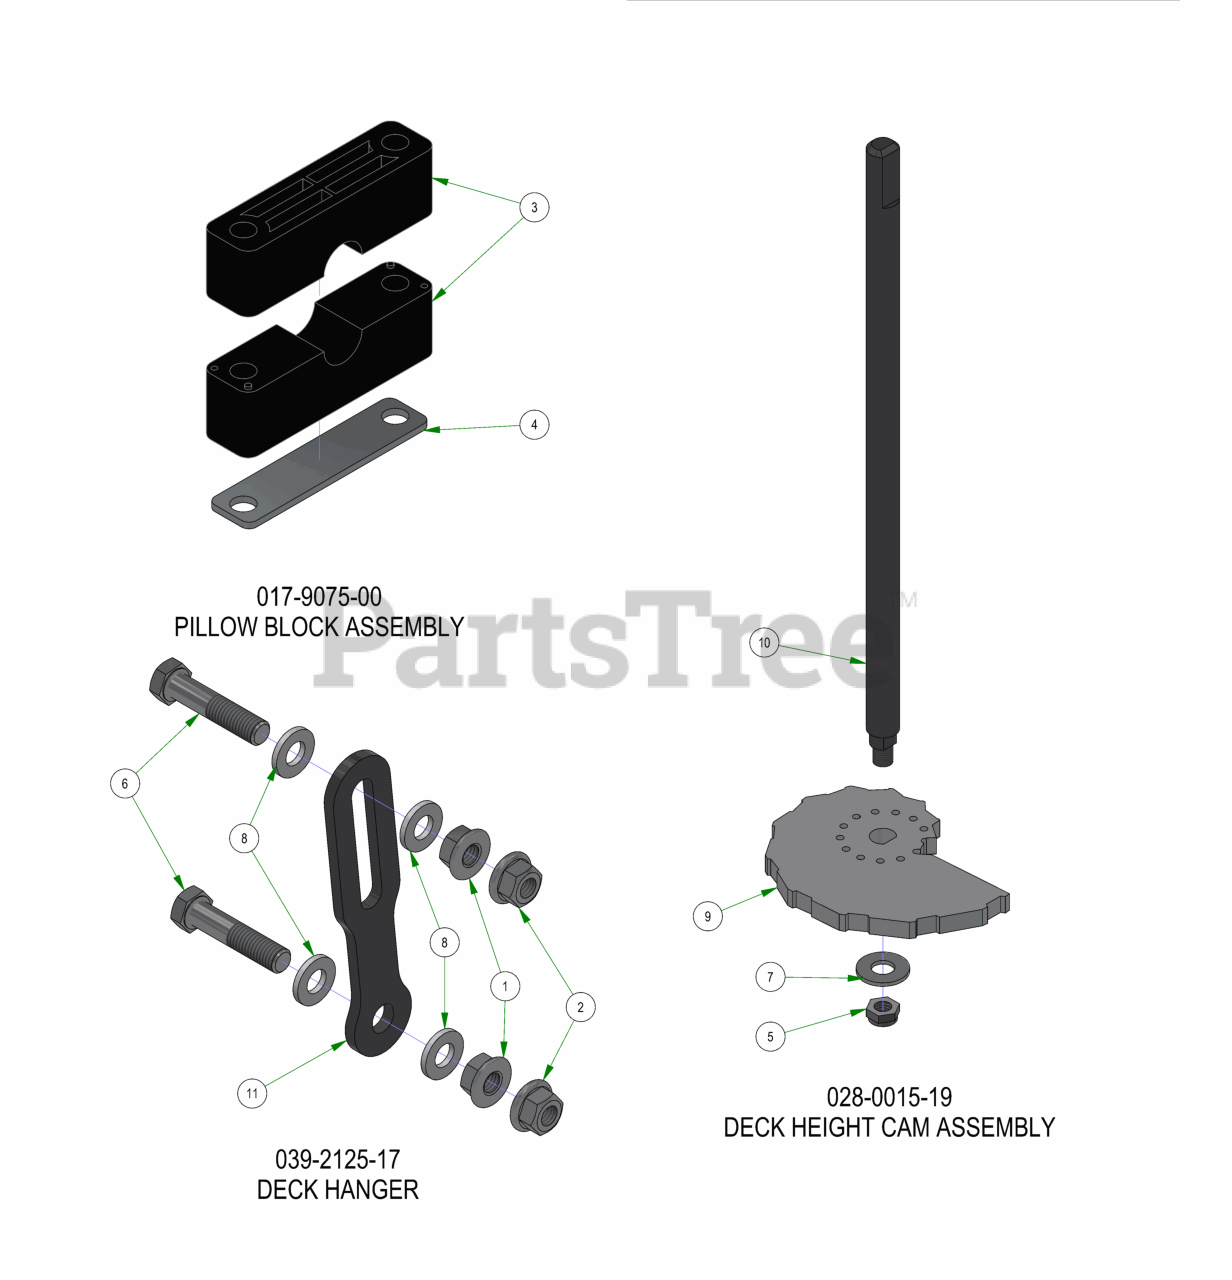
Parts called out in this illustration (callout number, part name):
1	1/2-13 HEX SERRATED FLANGE NUT HARD/ZINC
2	1/2-13 NYLON INSERT FLANGE LOCKNUT ZINC
3	Two Piece Pillow Block
4	Two Piece Pillow Block Strap
5	3/8-24 Nylon Insert jam locknut
6	1/2-13 X 2-1/4 HEX CAP SCREW (GR.5) ZINC
7	3/8 FLAT WASHER USS (1" OD) ZINC
8	.505 ID X 1.000 OD X .125 THICK FLAT WASHER NYLON
9	2019 Deck Height Cam
10	2019 Outlaw Gen2 Dial Rod
11	Deck Hanger
